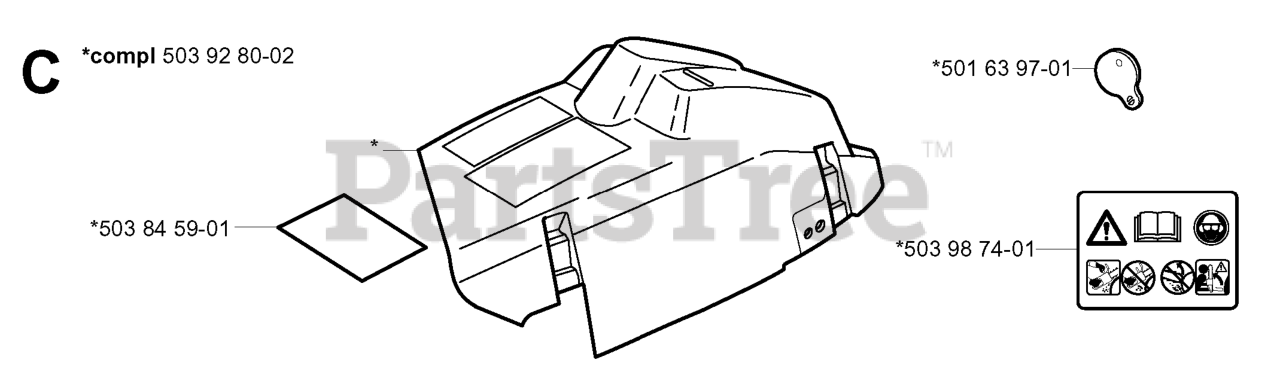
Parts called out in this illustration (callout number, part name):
2	DRAWBAR
3	SCREW 3/8-16X3/4
5	BUMPER DASH
6	PLATE
8	CLIP,INSULATOR
10	BOLT D
11	PANEL.DASH.LH.LTX
13	PANEL ASM, DASH RH
15	Screw, Machine, Truss Head 5/16-18 UNC x 3/4
16	NUT
17	HOOD
18	BUMPER.HOOD.TEX.HUSQVARNA
24	BOLT
25	WASHER
26	NUT
28	RP GRILLE/LENS ASM.
30	CONSOLE.CRD.AUTO.GRY
31	BRACKET SUPPORT FENDER
33	FOOTREST PNT LH
34	FOOTREST PNT RH
35	BOLT
37	Screw 5/16-18 x 1/2 Hex, Self Tapping 5/16-18 x 1/2
38	BRACKET ASM PIVOT MOWER REAR
39	BRACKET PIVOT
69	SCREW.HI-LO.CONSOLE
145	ROD PIVOT CHASSIS/HOOD
162	BRACKET
163	BRACKET EXTEN CHASSIS RH CRD
165	RP.COVER.BATTERY.CRD.GREY
171	BOLT
172	WASHER
175	DOOR TRAP
179	ROD PIVOT FBI
184	BRACKET.ACTUATOR.BAGGER.SRD
186	LATCH ASSY
187	WELDNUT
189	LOCKWASHER #10
190	SCREW
205	SCREW LT
207	SCREW, 5/16-18 X 1/2
208	SCREW 3/8-16X1/2
209	SCREW, 3/8-16X3/4
212	INSERT REFLECTIVE
213	SKIRT SIDE LH
214	SKIRT SIDE RH
216	SCREW HEXWSHR 1/4-20X3/4
256	COVER FENDER CRD
258	LENS.HUSQVARNA LT.RH
259	LENS.HUSQVARNA LT.LH
265	SEALING
266	SEALING
272	VENT SIDE HOOD RH
273	VENT SIDE HOOD LH
278	SCREW
295	VENT TOP HOOD
296	TRIM
297	CLIP.RETAINER.TINNER.
298	NUT PUSH M
299	RP LOGO
